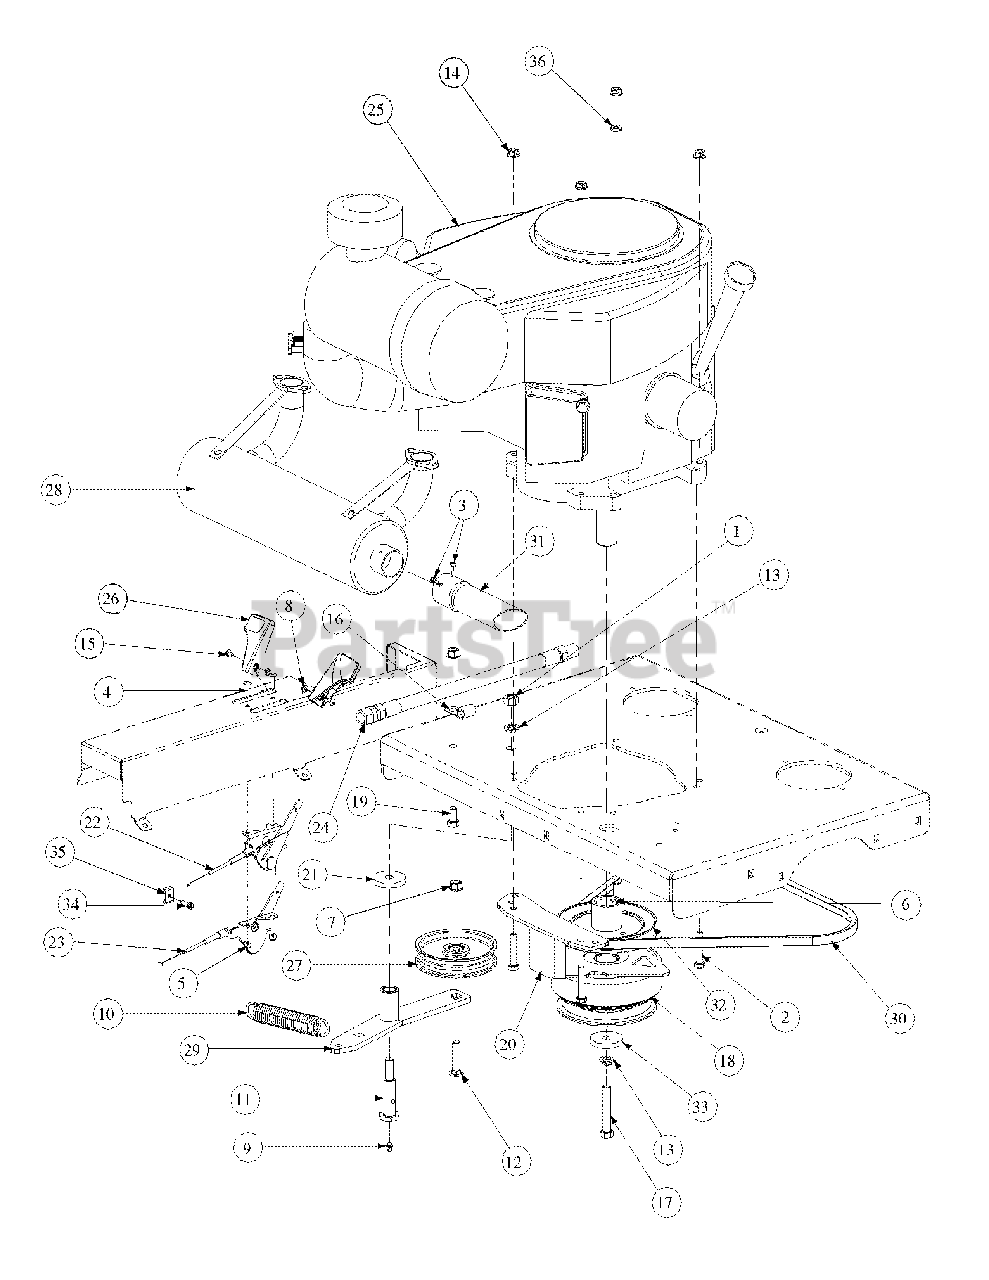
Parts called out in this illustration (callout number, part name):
1	Hex Nut, 7/16-14
2	HHCS, 5/16-18, 1-3/4
3	Screw, #8-32 x 0.375
4	Round Hd. Machine Screw, 10-32 x 3/4
5	Lock Nut, Nylon Insert, 10-32
6	Key, 1/4 x 1/4 x 3
7	Flange Lock, Hex Nut, 3/8-16
8	Nut Washer, W/Star, 8-32
9	Grease Fitting, 1/4-28 x 3/16
10	Extension Spring, 1.0 OD x 5.125
11	Shoulder Screw, 7/16-14
12	Hex Carriage Screw, 3/8-16, 1.75
13	Lock Washer, 7/16
14	Hexflange Lock Nut, 5/16-18
15	Machine Screw, 8-32, .375
16	Clip, Heat Shield Cable
17	Capscrew, 7/16-20 x 2.50
18	Clutch Brake, 1.125 ID
19	Hex Cap Screw, 3/8-16, .750
20	Retainer Clutch Assembly, Ogura
21	Flat Washer, 7/16 ID x 1.75 OD x .25
22	Choke, Control Cable, 43.0
23	Throttle, Control Cable, 39.0
24	Oil Drain Hose
25	19HP Twin Engine, Kawasaki
26	Control Throttle Knob
27	Flat Pulley with Flanges
28	Muffler Accessory, Kawasaki
29	Engine Idler Arm Assembly
29	Bearing
30	V Belt, A Section x .47.3
31	Muffler Accessory Exhaust Tube
32	Pump Drive Pulley
33	Flat Washer, 7/16 ID x 1.75 OD x .25
34	Bolt, M5 x 18
35	Choke Cable Clamp
36	Flat Washer, .320 ID x .591 OD x .078
